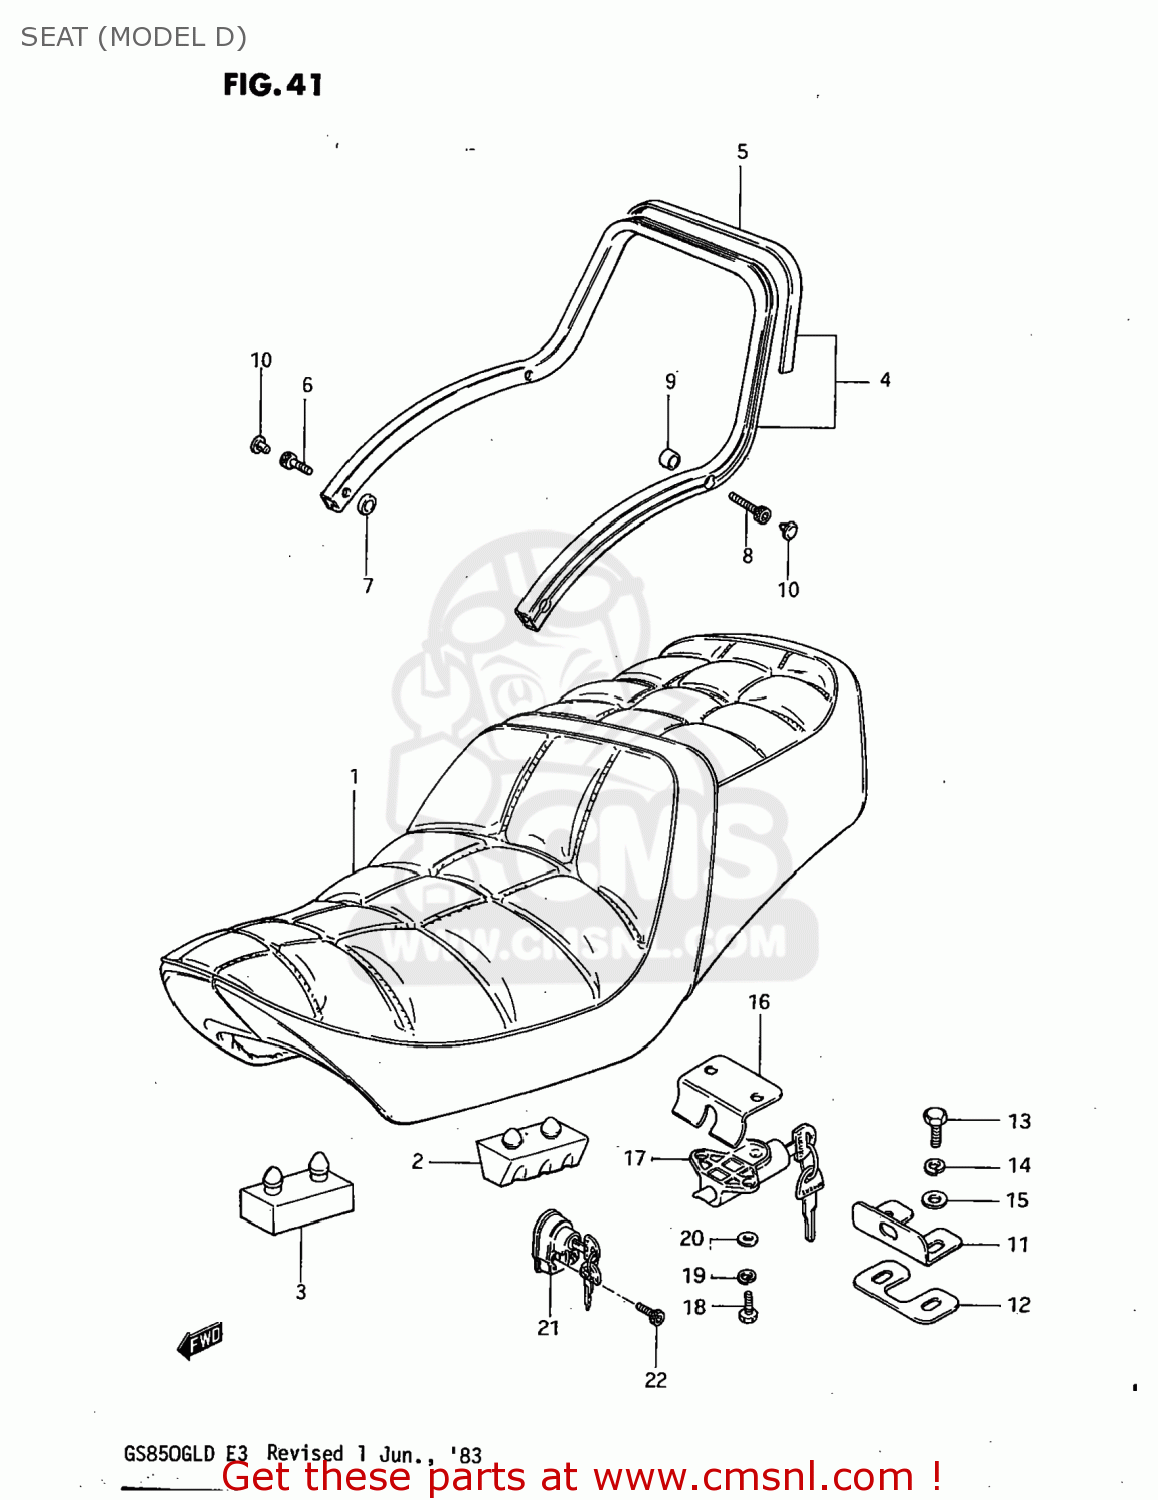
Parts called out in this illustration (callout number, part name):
1	SEAT ASSEMBLY
2	CUSHION,SUPPORT(50X25X32)
3	CUSHION
4	HANDLE,PILLION RIDER
5	RUBBER,PILLION RIDER HANDLE
6	BOLT
7	SPACER,REAR
8	BOLT
9	SPACER,REAR
10	CAP(OD:14.5)
11	STRIKER,SEAT LOCK
12	SHIM,SEAT LOCK STRIKER
13	BOLT, UPPER
14	LOCK WASHER
15	WASHER
16	PLATE,SEAT LOCK
17	LOCK ASSEMBLY,SEAT
18	BOLT
19	LOCK WASHER
20	WASHER 6MM
21	LOCK ASSY,HELMET
22	BOLT 5X25
